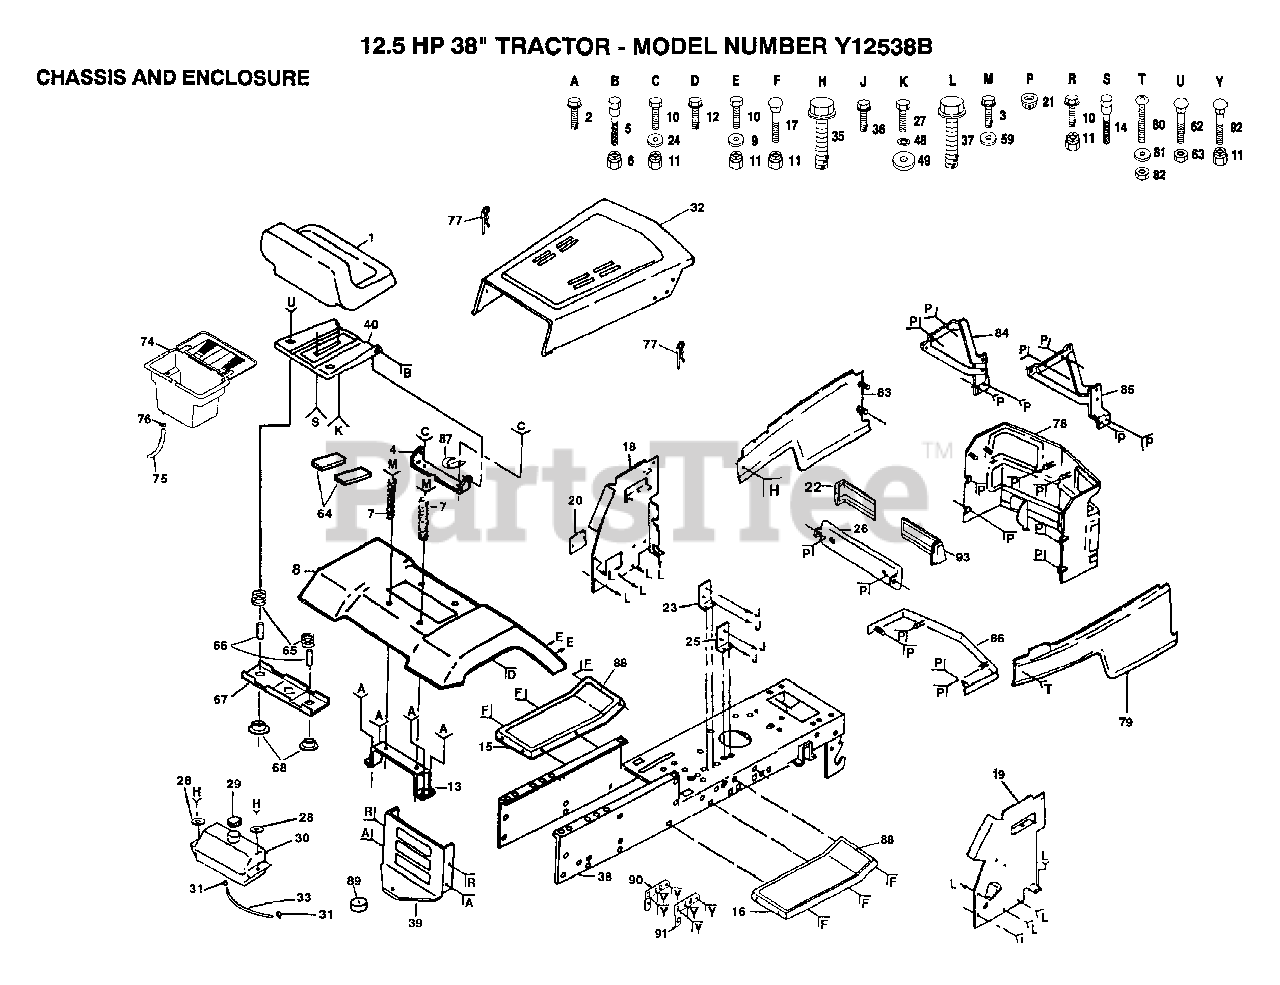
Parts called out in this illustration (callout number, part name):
2	SCREW
3	SCREW GTV
7	SPRING COMPRESSIO
8	FENDER
9	WASHER
12	SCREW LT
14	"BOLT,SHOULDER"
17	BOLT
18	PANEL DASH LH
20	COVER ACCESS
21	PAL NUT LT
23	SWITCH BRACKET
24	WASHER
25	BRACKET LT
27	BOLT
28	WASHER
30	TANK.FUEL.LT.
31	HOSE CLAMP
33	FUEL LINE T
35	SCREW HEX CRT
36	SCREW
37	SCREW LT
39	DRAWBAR LT/YT
48	LOCKWASHER
49	WASHER
59	WASHER
64	STRIP FORM
65	SPRING
66	SPACER SPLIT
67	BRKT SWITCH
68	BUSHING
76	HOSE CLAMP T
77	SPRING.RETAINER
79	SIDE PANEL ASM RH
80	"SCREW,SPECIAL"
82	RETAINER
83	SIDE PANEL ASM LH
84	"HINGE,HOOD,LH T"
85	"HINGE,HOOD,RH T"
86	STRAP ASM GRILL
87	CLIP T
88	FOOTREST PAD
90	BRKT ASM PIVOT LH
91	BRKT ASM PIVOT RH
92	BOLT
